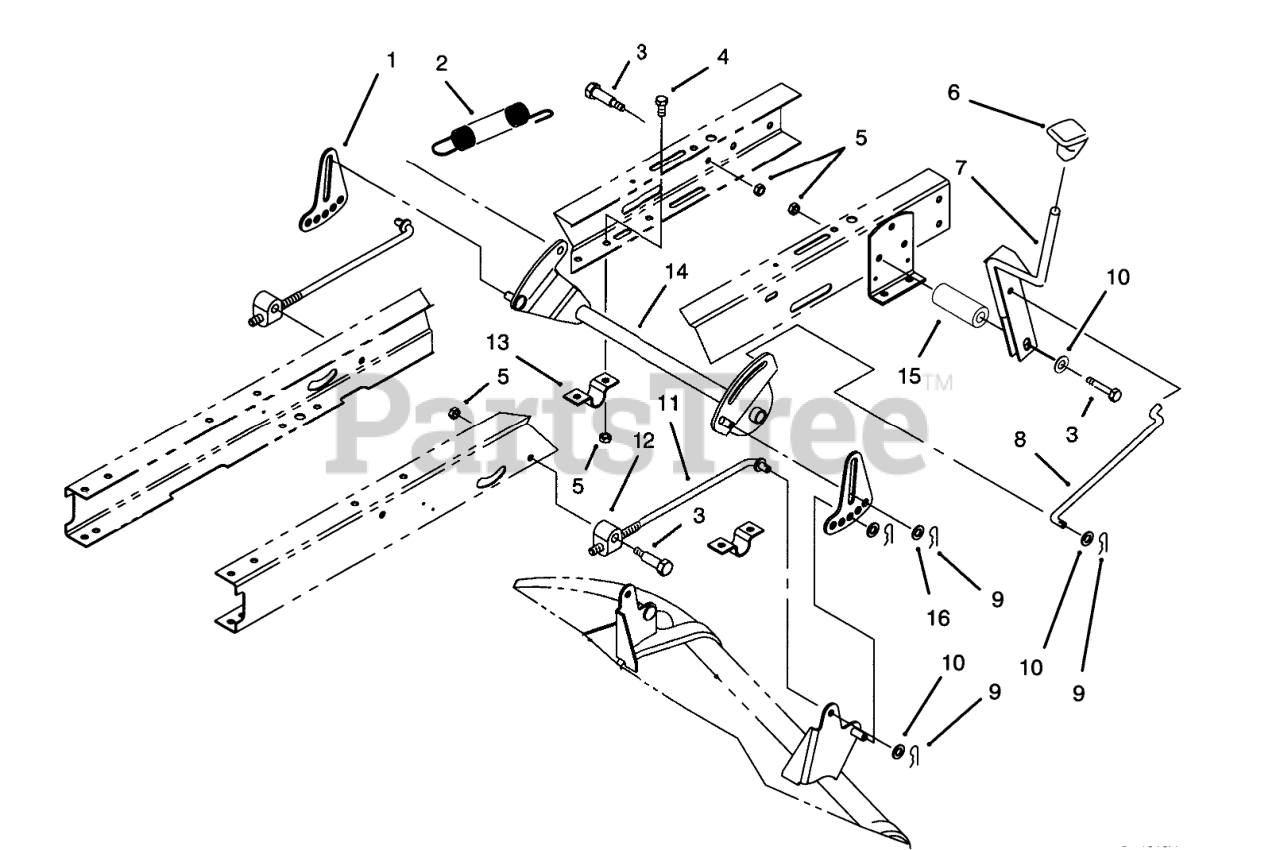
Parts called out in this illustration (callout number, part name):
1	Link-Adjusting H.O.C
2	SPRING-EXTENSION
3	SCREW-SHOULDER, HH
4	SCREW-HH
5	NUT-LOCK, NI
6	SHIFT KNOB
7	Lever-H.O.C.
8	LINK-HOC
9	PIN-COTTER
10	WASHER-FLAT
11	ROD-HANGER, REAR
12	TRUNNION-HOC
13	CLAMP-PIVOT, HOC
14	Pivot-H.O.C.
15	SPACER
16	WASHER-HARDENED
